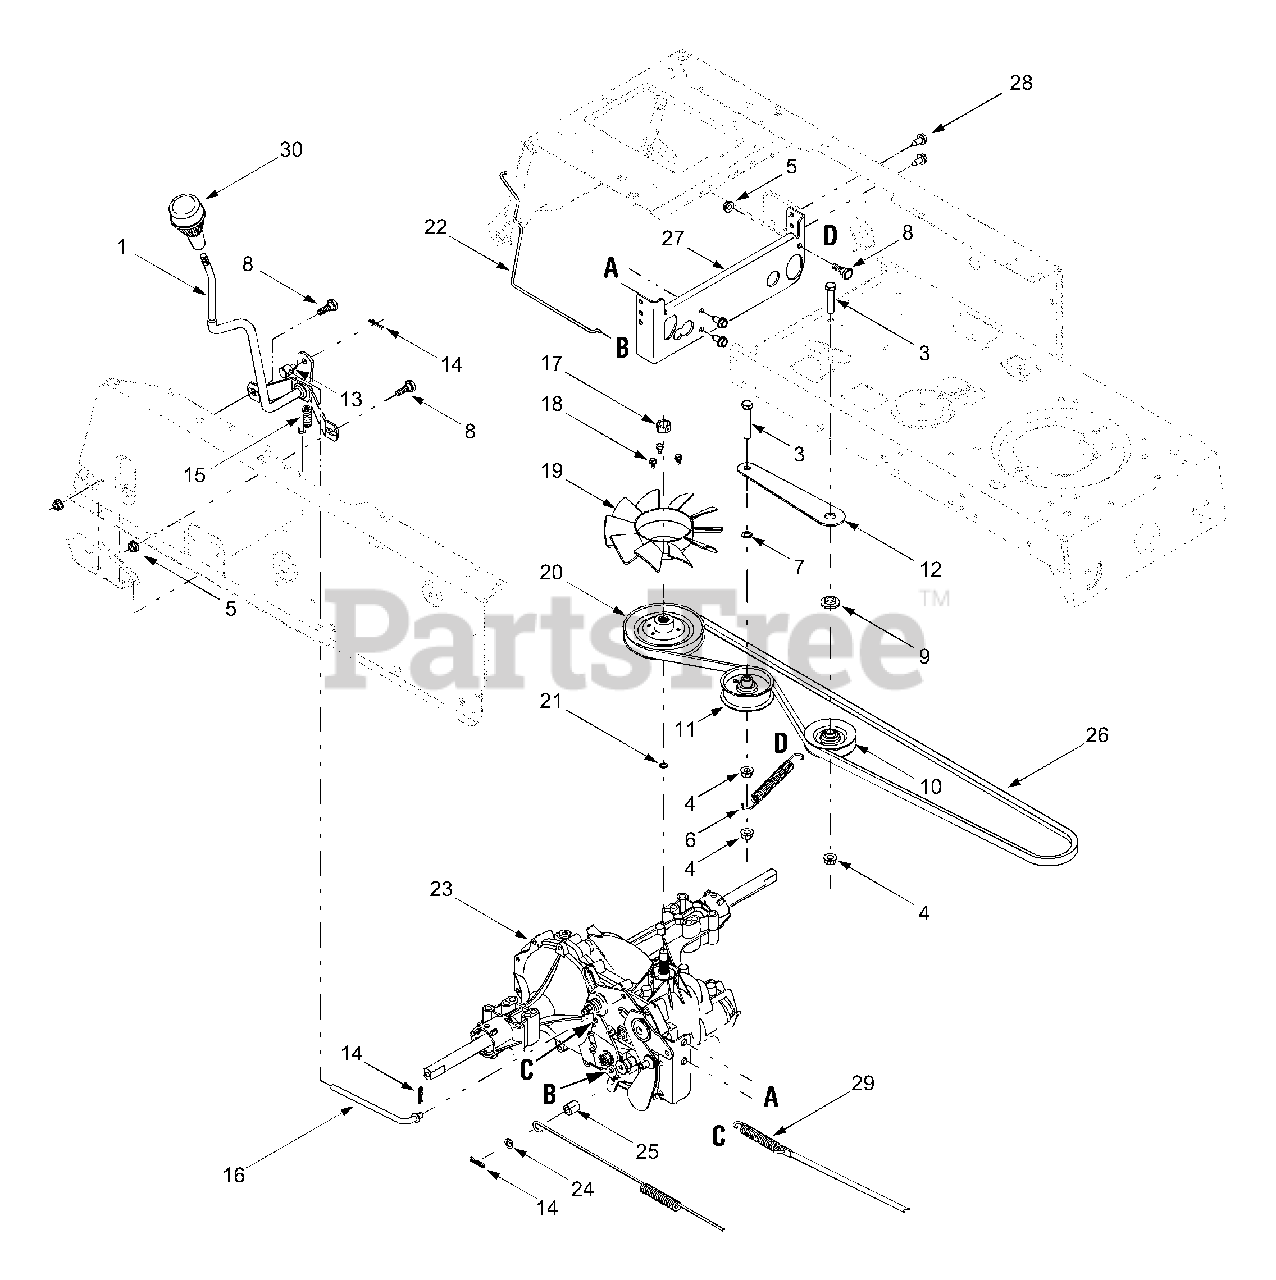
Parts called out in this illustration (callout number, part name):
1	Lever, Speed Control
3	Hex Screw, 3/8-16 x 2.25
4	Flange Lock Nut, 3/8-16
5	Flange Lock Nut, 5/16-18
6	Extension Spring, .62 x 6.38
7	Flat Washer, .375 x .62 x .033
8	Shoulder Screw, .437 x .286
9	Shoulder Spacer, .625 x 1.16
10	V-Type Idler Pulley, 3.06
11	Flat Idler Pulley, 2.75
14	Cotter Pin
15	Extension Spring, .50 x 2.54
16	Hydrostatic Control Rod
17	Hex Lock Nut, 1/2-20
18	Screw, #12-24 x .375
19	Fan Blade, 10
20	Transmission Pulley, 5.0
21	Ring Wire
22	Hydrostatic Bypass Rod
23	Hydrostatic Transmission
24	Flat Washer, .385 x .62 x .063
25	Spacer, .385 x .625 x .700
26	Belt
29	Extension Spring, .59 x 4.0
